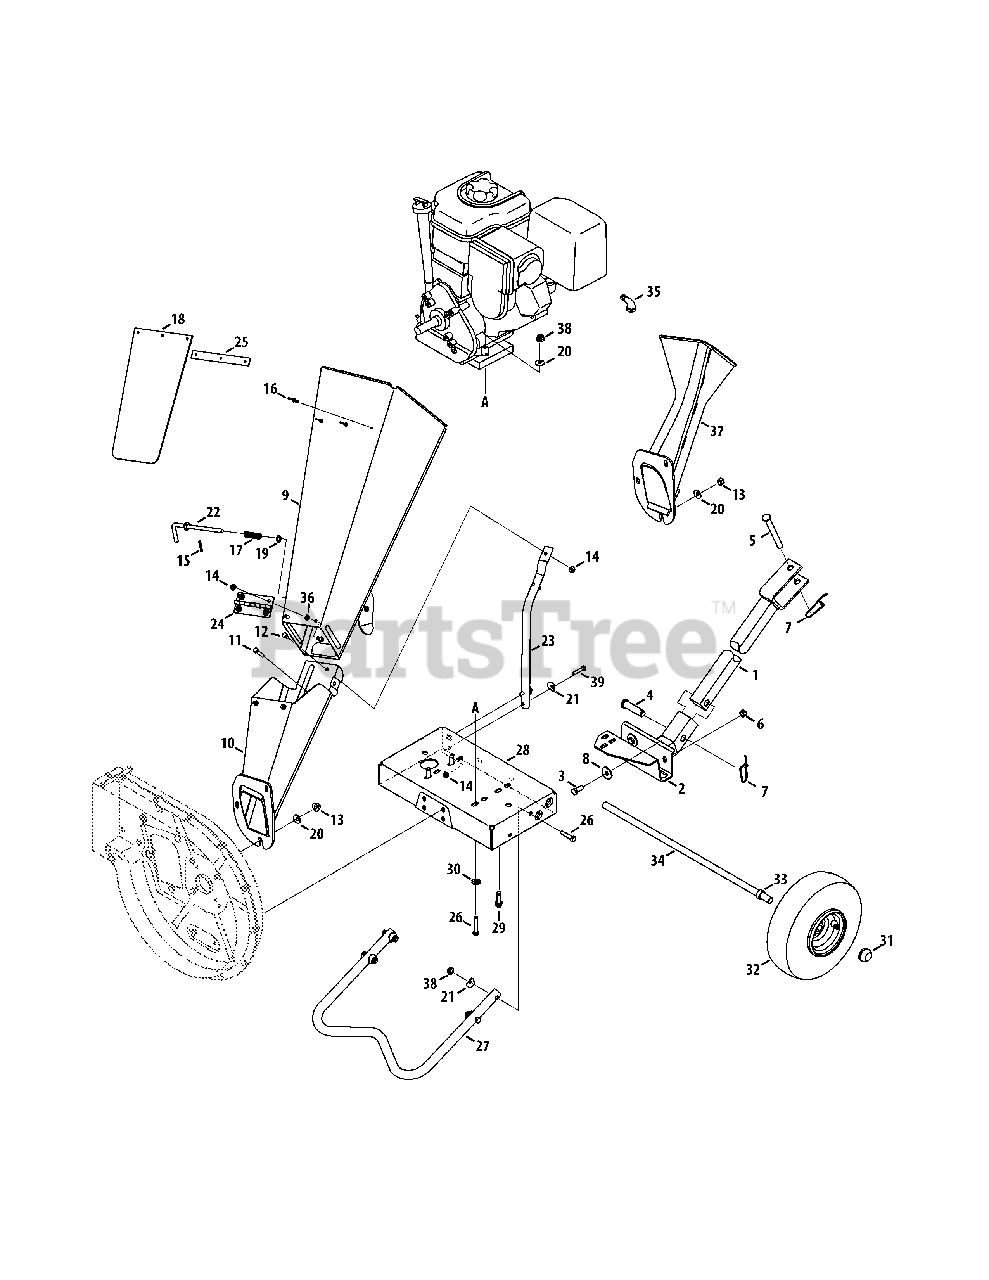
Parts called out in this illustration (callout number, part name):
1	Tongue Hitch Mount
2	Base Hitch Mount
3	Hex Cap Screw, 3/8-16 x.88
4	Clevis Pin,.625 x 2.4
5	Clevis Pin,.50 x 4.62
6	Flange Lock Nut, 3/8-16
7	Spring Pin
8	Flat Washer,.411 x 1.25 x 1.0
9	Upper Chipper Chute Assembly
10	Lower Chipper Chute Assembly
11	Hex Cap Screw, 1/4-20 x 1.25
12	Screw, 1/4-20 x .50
13	Hex Nut, 5/16-18
14	Flange Lock Nut 1/4-20
15	Cotter Pin
16	Pop Rivet
17	Compression Spring,.531 x 1.75
18	Chute Flap
19	Flat Washer
20	Bell Washer.340 ID x.872 OD
21	Washer,.320 ID x.93 OD
22	Lock Rod
23	Chipper Chute Support
24	Chipper Chute Hinge
25	Chute Flap Strip
26	Hex Cap Screw, 5/16-18 x 1.50
28	Frame Assembly
29	Hex Sems Screw, 3/8-16 x 1.25
30	Special Lock Washer, 5/16
31	Push Cap, 5/8
32	Wheel, 10 x 4 x 4
33	Spacer, .64 x .88 x .38
34	Axle, 22.47"
35	Elbow Fitting
36	Push Nut,.25ID x.50OD
37	Chipper Chute
38	Flange Lock Nut, 5/16-18
39	Hex Cap Screw, 1/4-20 x 1.250
